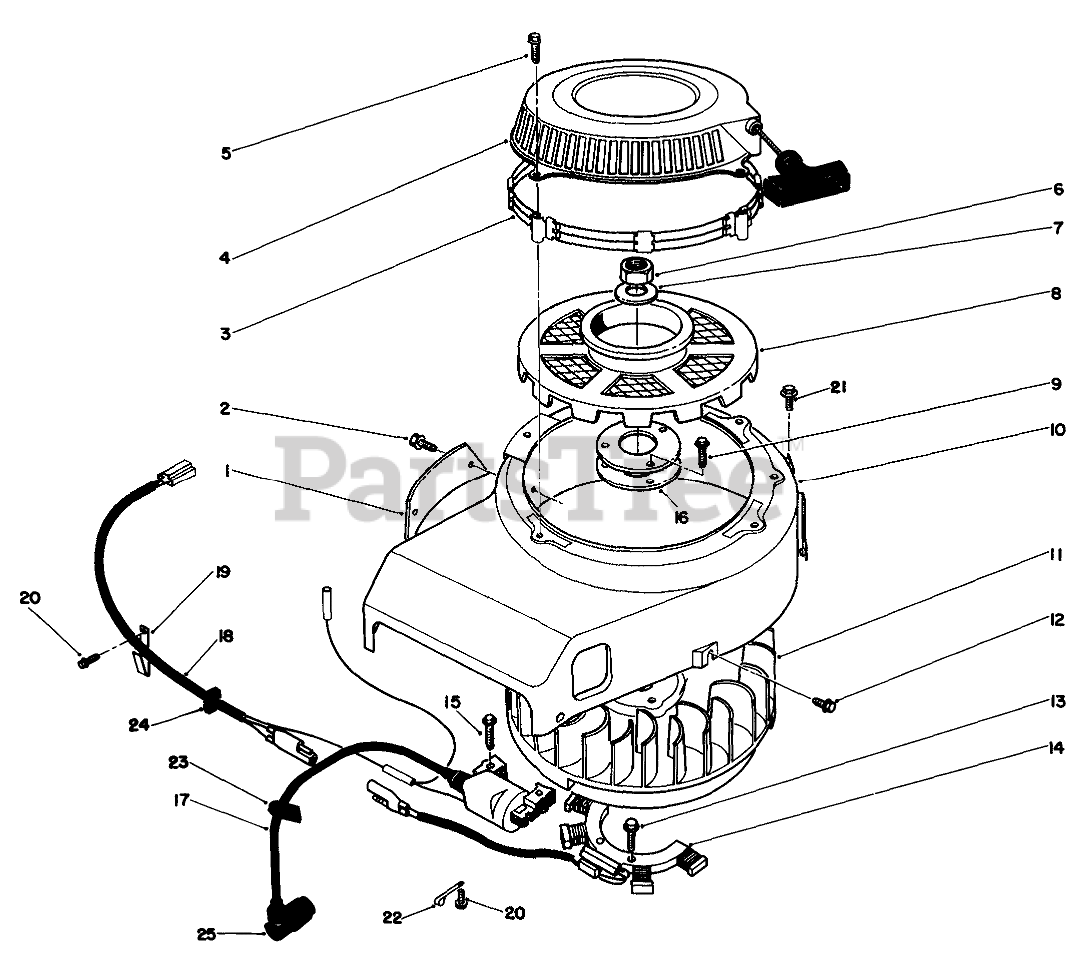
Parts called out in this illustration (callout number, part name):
1	Cover
4	Recoil Starter ASM
5	Bolt-Flanged (6X35)
9	Bolt-Flanged (8X12)
10	Housing-Fan
11	Flywheel
12	BOLT-FLANGED (6X10)
15	Bolt
17	Coil
19	Clamp
20	Bolt-Flanged (6X10)
21	Bolt-Flanged (6X14)
25	Cap-Spark
